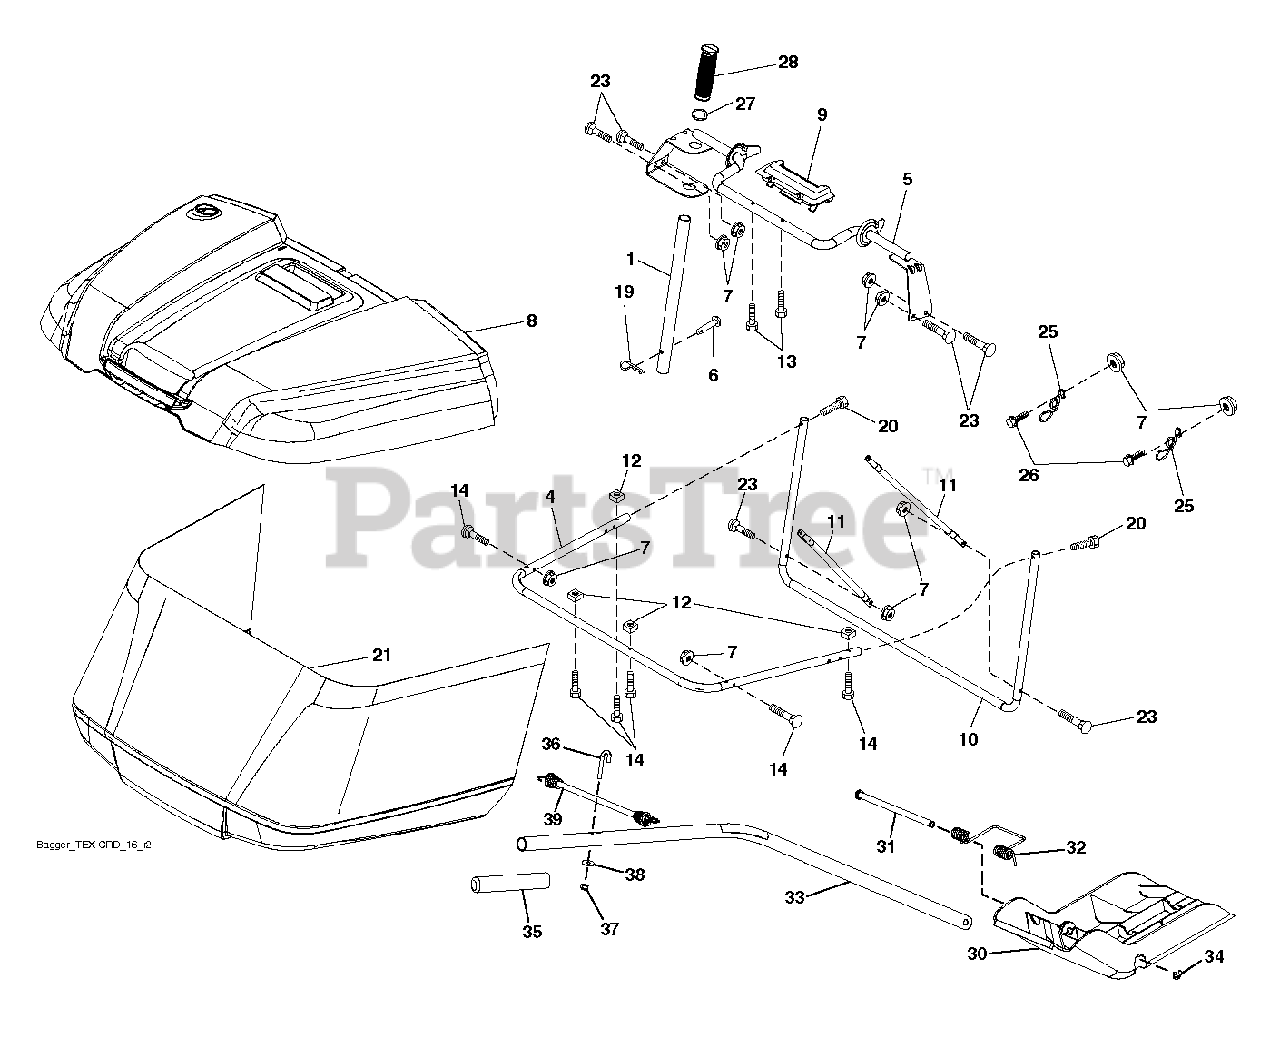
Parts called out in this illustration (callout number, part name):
1	TUBE.PNT.HDL.BAGGER.
6	RIVET,DRILLED
7	NUT T
19	PIN.COTTER.5/16.BOW TI
20	SCREW.HEXCAP.1/4-20X1.375(2 2)
26	SCREW HEX CRT
28	GRIP.HANDLE.BLACK
34	E-RING.5/16"
38	WASHER
